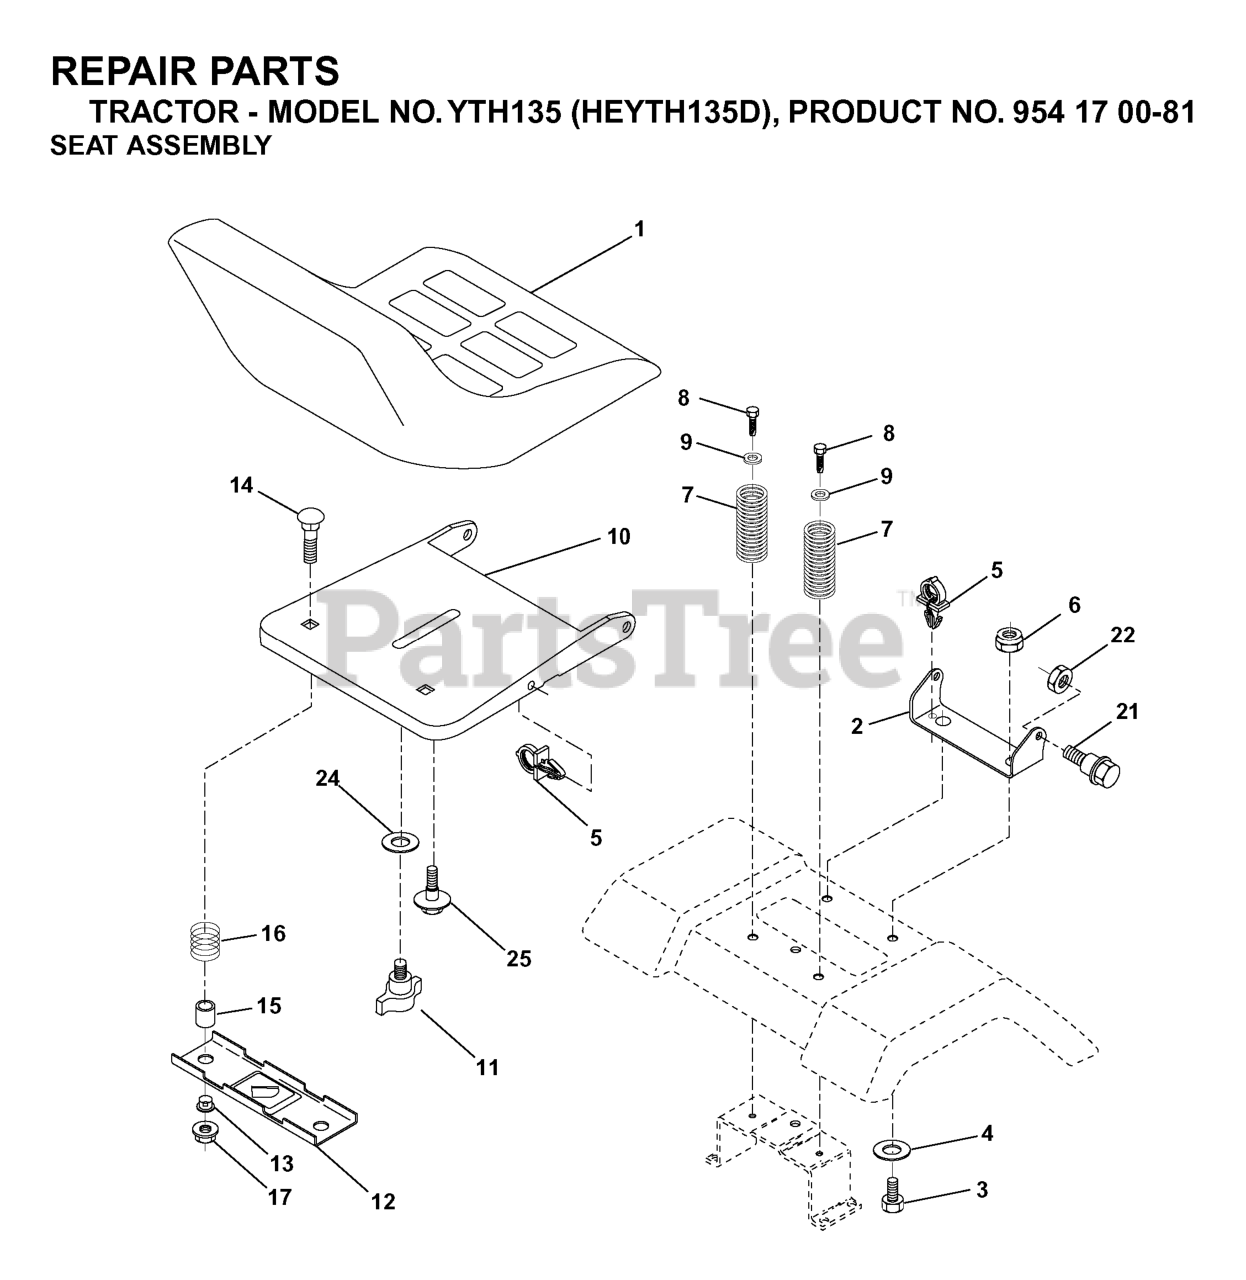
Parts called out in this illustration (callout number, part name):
1	SEAT, GRAY
2	SEAT PIVOT BRKT
3	BOLT, HEX 3/8-16X1
6	NUT
7	SPRING COMPRESSION
8	SCREW 3/8-16X1
9	WASHER
10	PAN SEAT
11	KNOB.SEAT.ADJ.WINGNUT
12	BRKT SWITCH
14	BOLT.ROUND.HEAD.SQUARE.NECK
15	SPACER SPLIT 28X.96
17	NUT T
21	BOLT.SHOULDER.5/16-18
22	NUT.71038.31-18.HEX.NYLOCK
24	WASHER GT
25	BOLT,SHOULD
